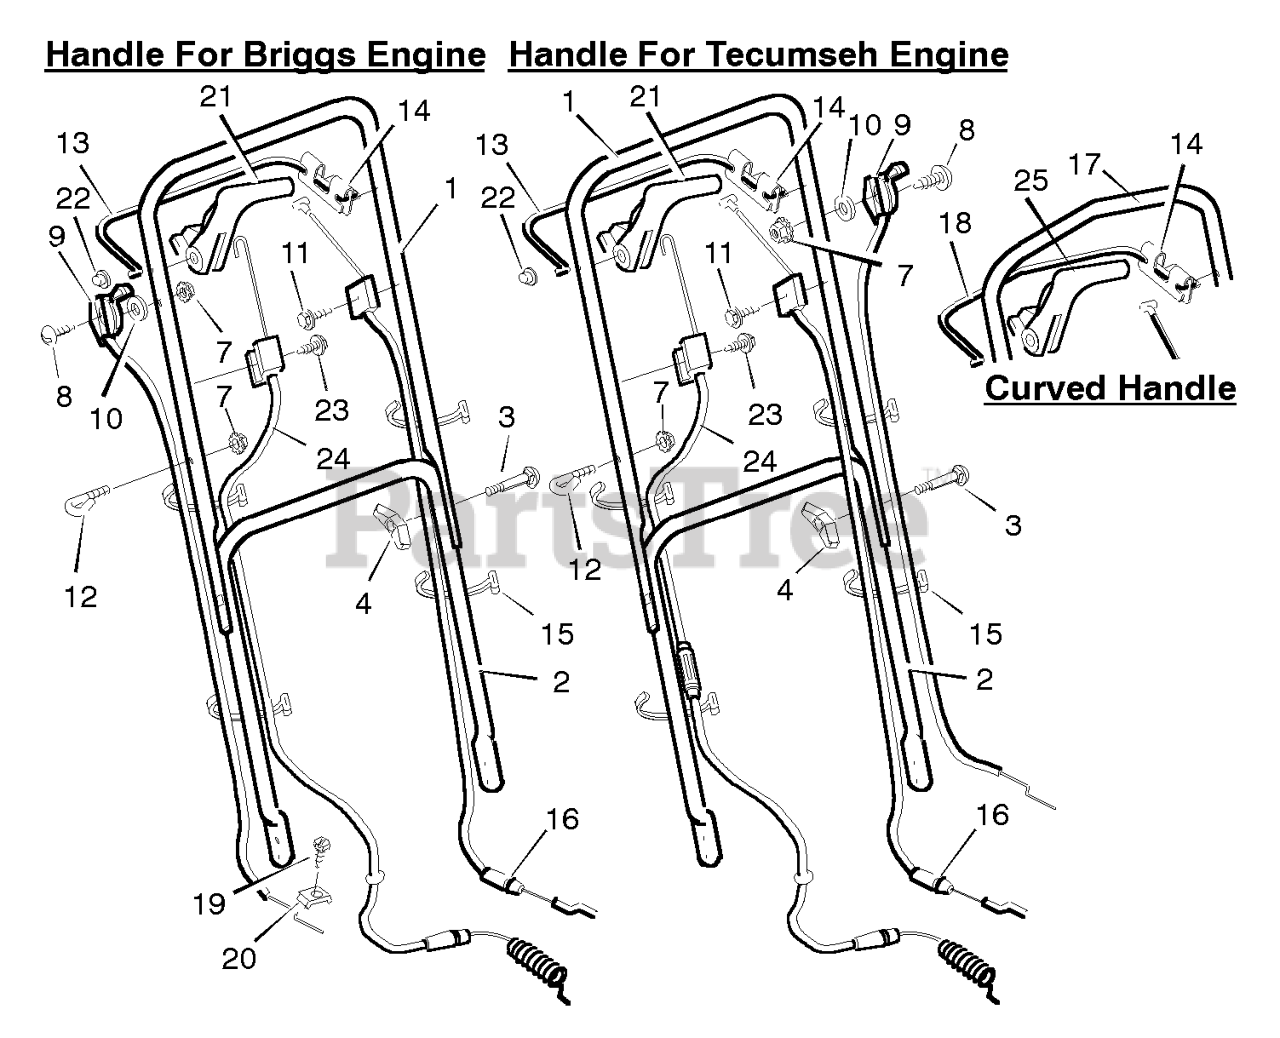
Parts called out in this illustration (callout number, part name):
1	Handle, Upper-Straight (Black)
2	Handle, Lower (Black)
4	Knob, Plastic
7	Locknut
9	Throttle Control
10	Washer
12	GUIDE, ROPE
13	Stop Lever - Straight
14	Bracket, Stop Lever
15	Fastener, Cable
16	Engine Stop Cable *
17	Handle, Upper- Curved (Black)
18	Stop Lever - Curved
19	Screw *
20	Clamp
21	Lever, Drive - Straight
22	Push On Cap
24	Cable, Drive
25	Lever, Drive - Curved
